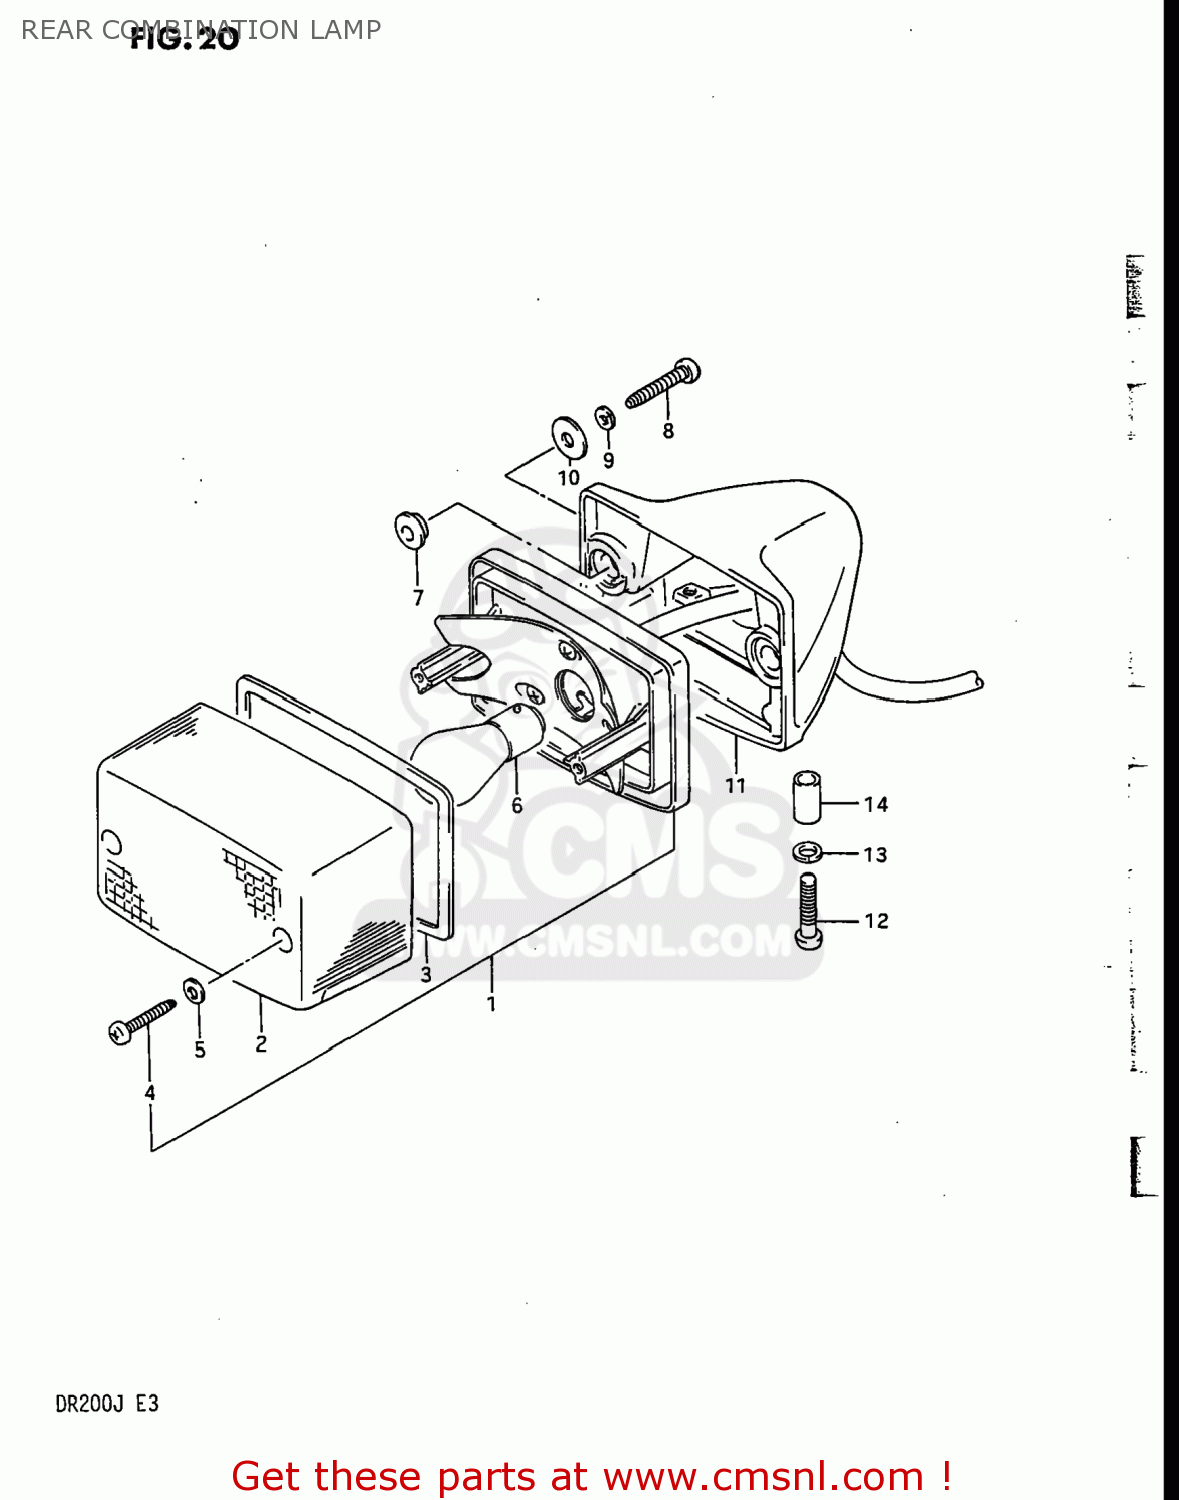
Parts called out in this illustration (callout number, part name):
1	LAMP UNIT,REAR COMBINATION
2	LENS,REAR COMBINATION LAMP
3	GASKET,RR COMBI LAMP LENS (NAS)
4	SCREW
5	GASKET (NAS)
6	BULB(6V5W,TOKAI DENSO)
7	SPACER,RR COMBI
8	SCREW
9	WASHER,LOCK
10	WASHER
11	BRACKET UNIT,TAIL LAMP
12	SCREW
13	WASHER,LOCK
14	SPACER(6.4X9.2X12)
